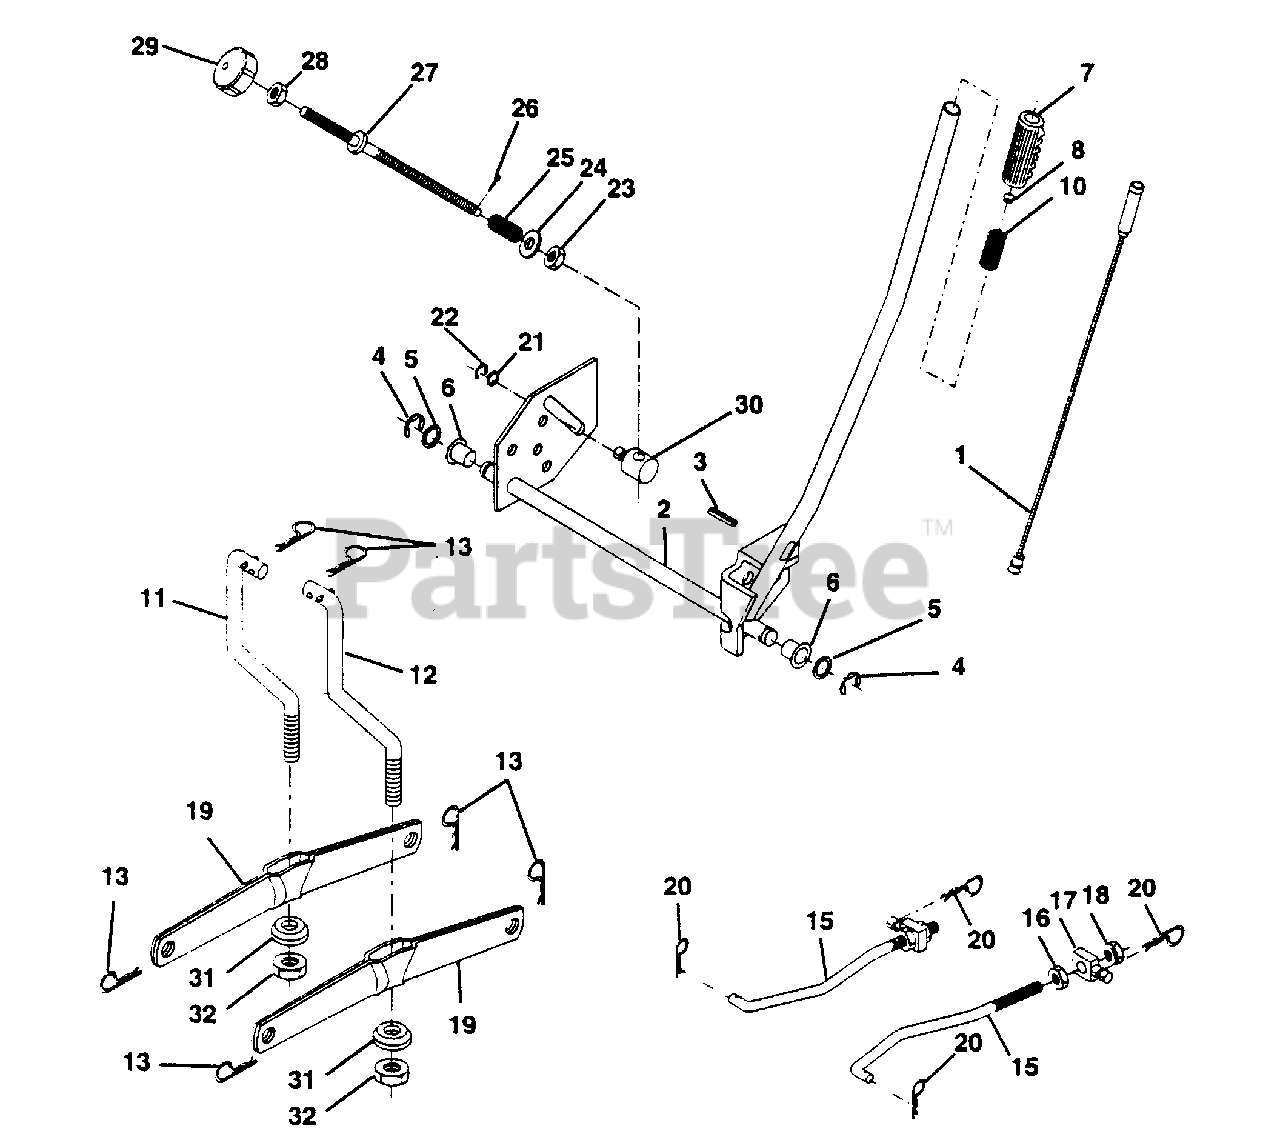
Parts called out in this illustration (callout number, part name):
1	Wire Asm Inner W/plunger 20 56 (AYP part number)
2	Shaft Asm Lift RH w/Inf W/T (AYP part number)
3	Pin Groove 1 500 Zinc (AYP part number)
4	E Ring #5133-62 (AYP part number)
5	Washer 21/32 X 1 X 21 Ga (AYP part number)
6	Bearing Nylon Blk 629 Id (AYP part number)
7	Grip Handle Bicycle (AYP part number)
8	Button Plunger Black (AYP part number)
10	Spring Cprsn 3 750 Oiled
11	Link Lift LH Fixed Length (AYP part number)
12	Link Lift RH Fixed Length
13	Retainer Spring (AYP part number)
15	Link Front (AYP part number)
16	Nut Jam Hex 1/2-13 Unc (AYP part number)
17	Trunnion Blk Zinc (AYP part number)
18	Nut Lock W/wsh 1/2-13unc (AYP part number)
19	Arm Suspension Rear (AYP part number)
20	Retainer Spring (AYP part number)
21	Washer 15/32 X 3/4 X 16 Ga (AYP part number)
22	Ring Klip #t5304-37 (AYP part number)
23	Nut Special (AYP part number)
24	Washer 13/32 X 5/8 X 16 Ga (AYP part number)
25	Spring 2-1/8" (AYP part number)
26	Pin Cotter 3/32 X 1/2 (AYP part number)
27	Rod Adj Lift Zinc 9 00 Wrk Lg (AYP part number)
28	Nut Hex Jam 3/8-16 Unc (AYP part number)
29	Knob Inf 3/8-16 Unc Blk W/sym (AYP part number)
30	Trunnion Dp Stop Dbl Thds PLT
31	Bearing Pvt Lift Spherical (AYP part number)
32	Nut Nylock 3/8-24 (AYP part number)
